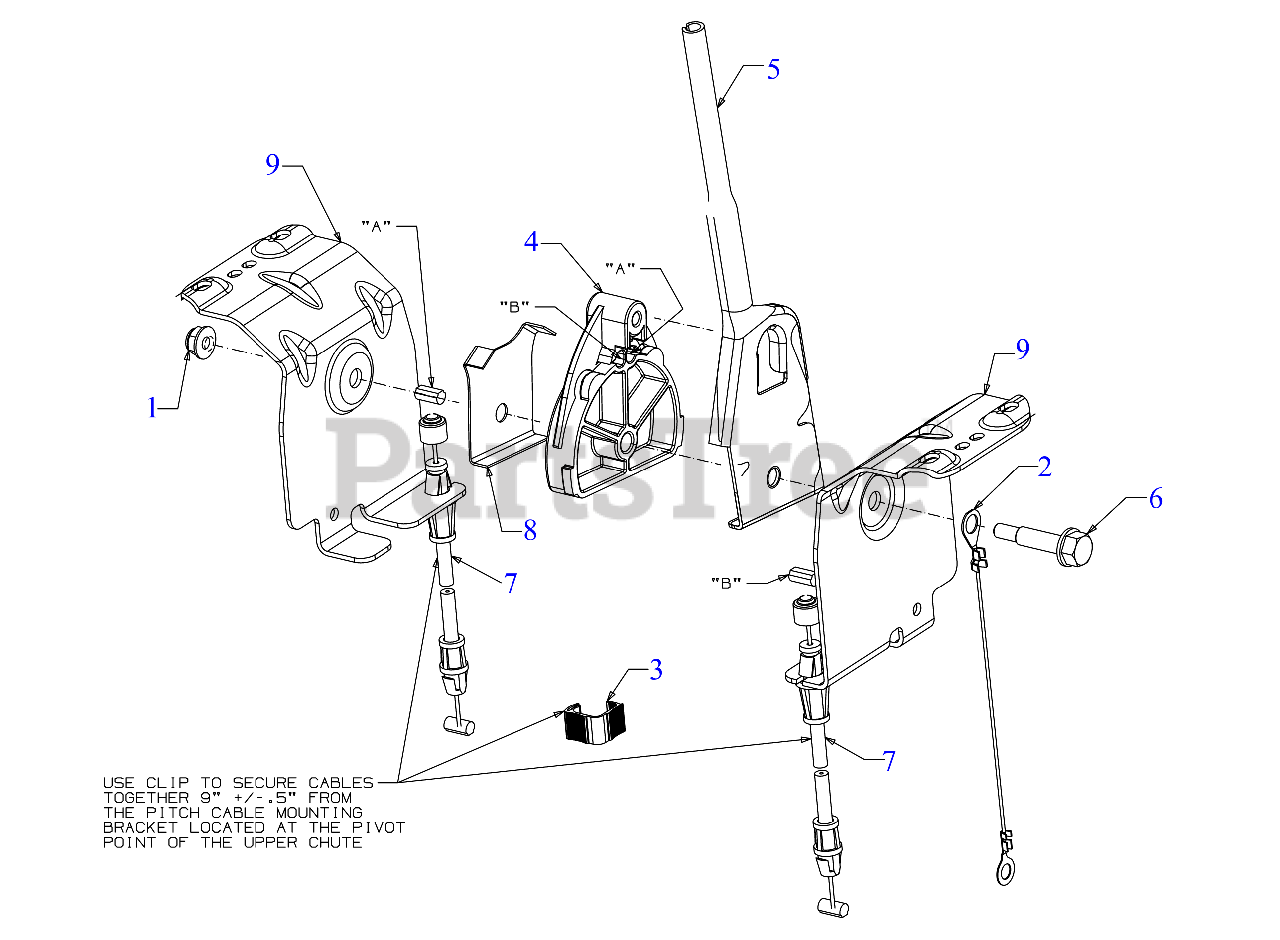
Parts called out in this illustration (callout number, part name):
1	FLANGE LOCK NUT
2	CHUTE GROUND WIRE
3	CABLE CLIP
4	CABLE GUIDE
5	SHIFT LEVER
6	SHOULDER SCREW
7	2-WAY PITCH CONTROL CABLE
8	CHUTE BRACKET GROUND
